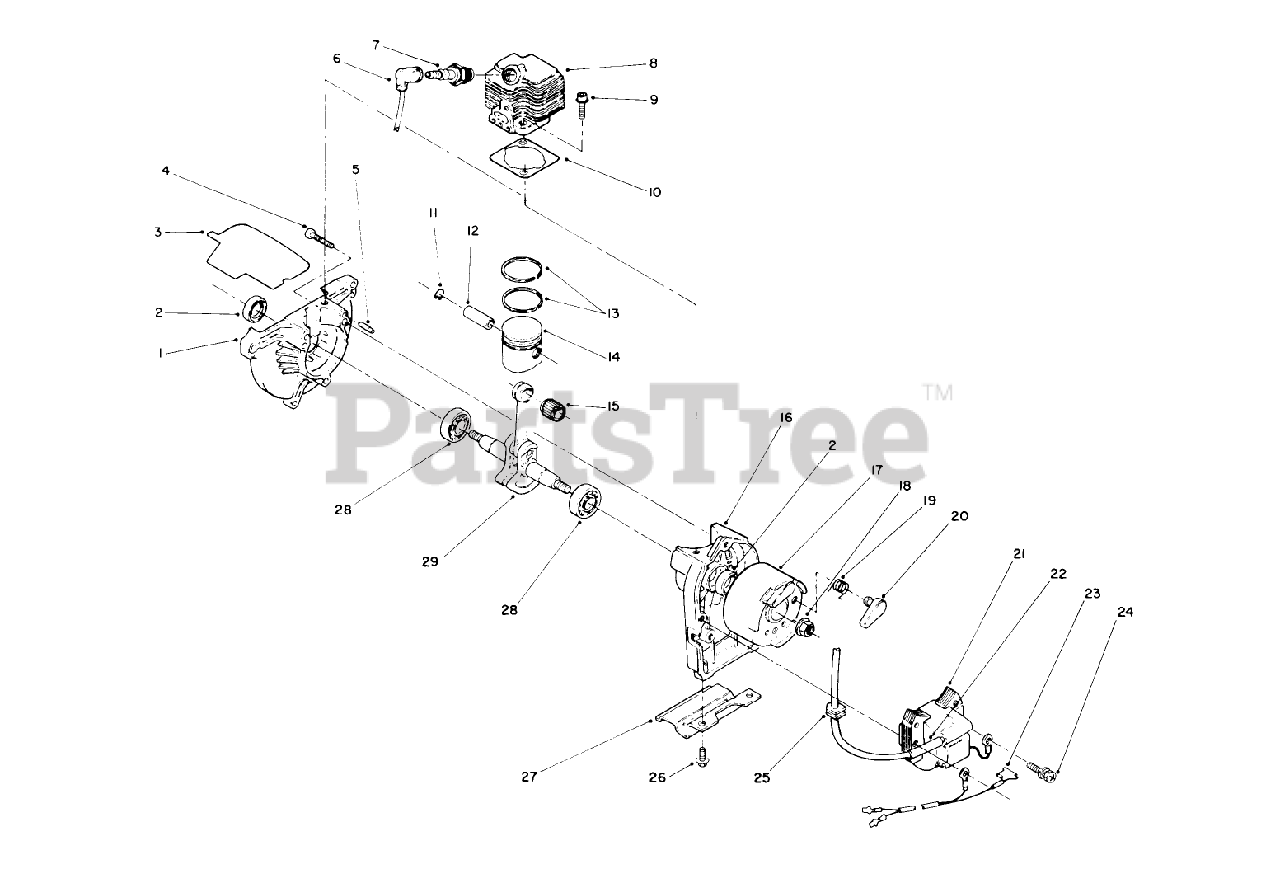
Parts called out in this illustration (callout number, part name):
2	OIL SEAL
8	CYLINDER
11	PISTON PIN CLIP
13	TOP RING
14	PISTON SET
20	RATCHET
24	BOLT AND WASHER
28	BEARING
